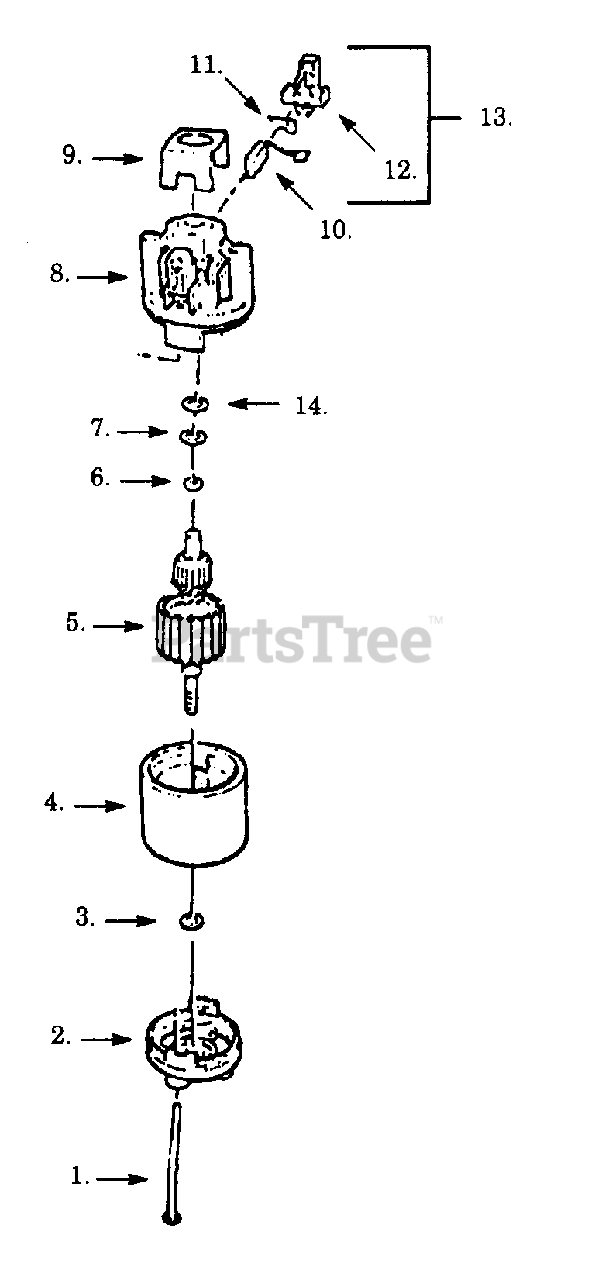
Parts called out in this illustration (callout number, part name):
2	Endbell Ass'y. (Drive)
4	Field Ass'y.
5	Armature Ass'y.
8	Endbell Ass'y. (Brush)
9	Insulator
10	Carbon Brush
11	Brush Spring
12	Brush Holder
13	Brush Kit
14	Retaining Ring
